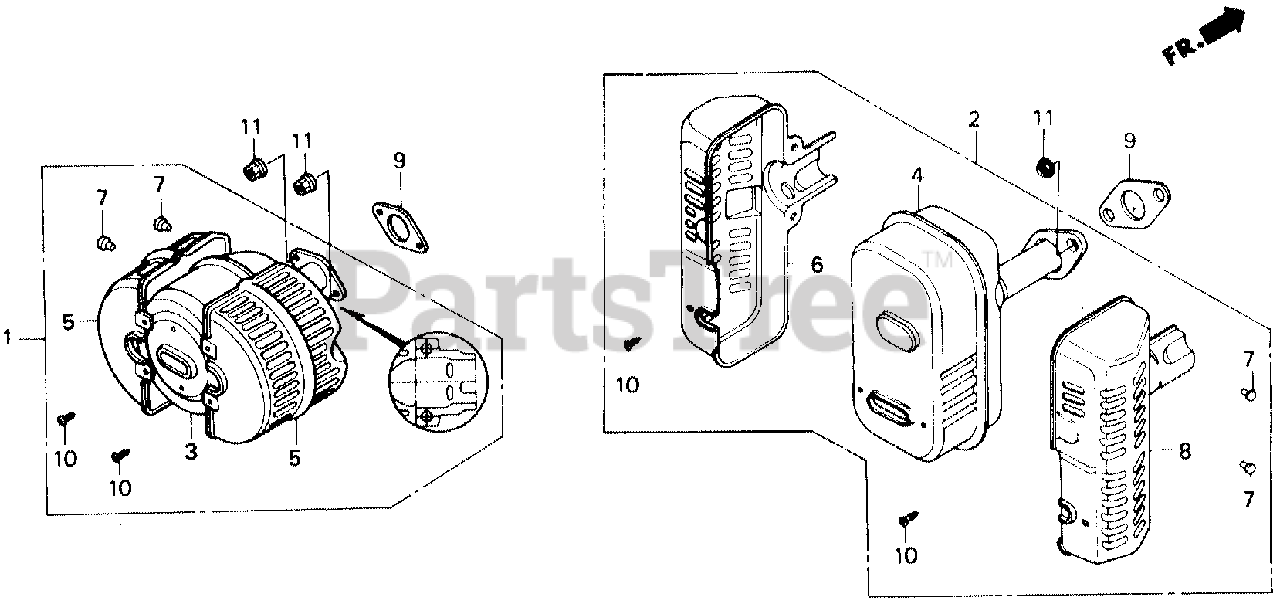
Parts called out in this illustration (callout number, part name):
2	MUFFLER ASSY.
4	MUFFLER
6	PROTECTOR, L. MUFFLER
7	RIVET (4X5)
8	PROTECTOR, R. MUFFLER
9	GASKET, MUFFLER
10	SCREW, TAPPING (4X8)
11	NUT, FLANGE (8MM)
